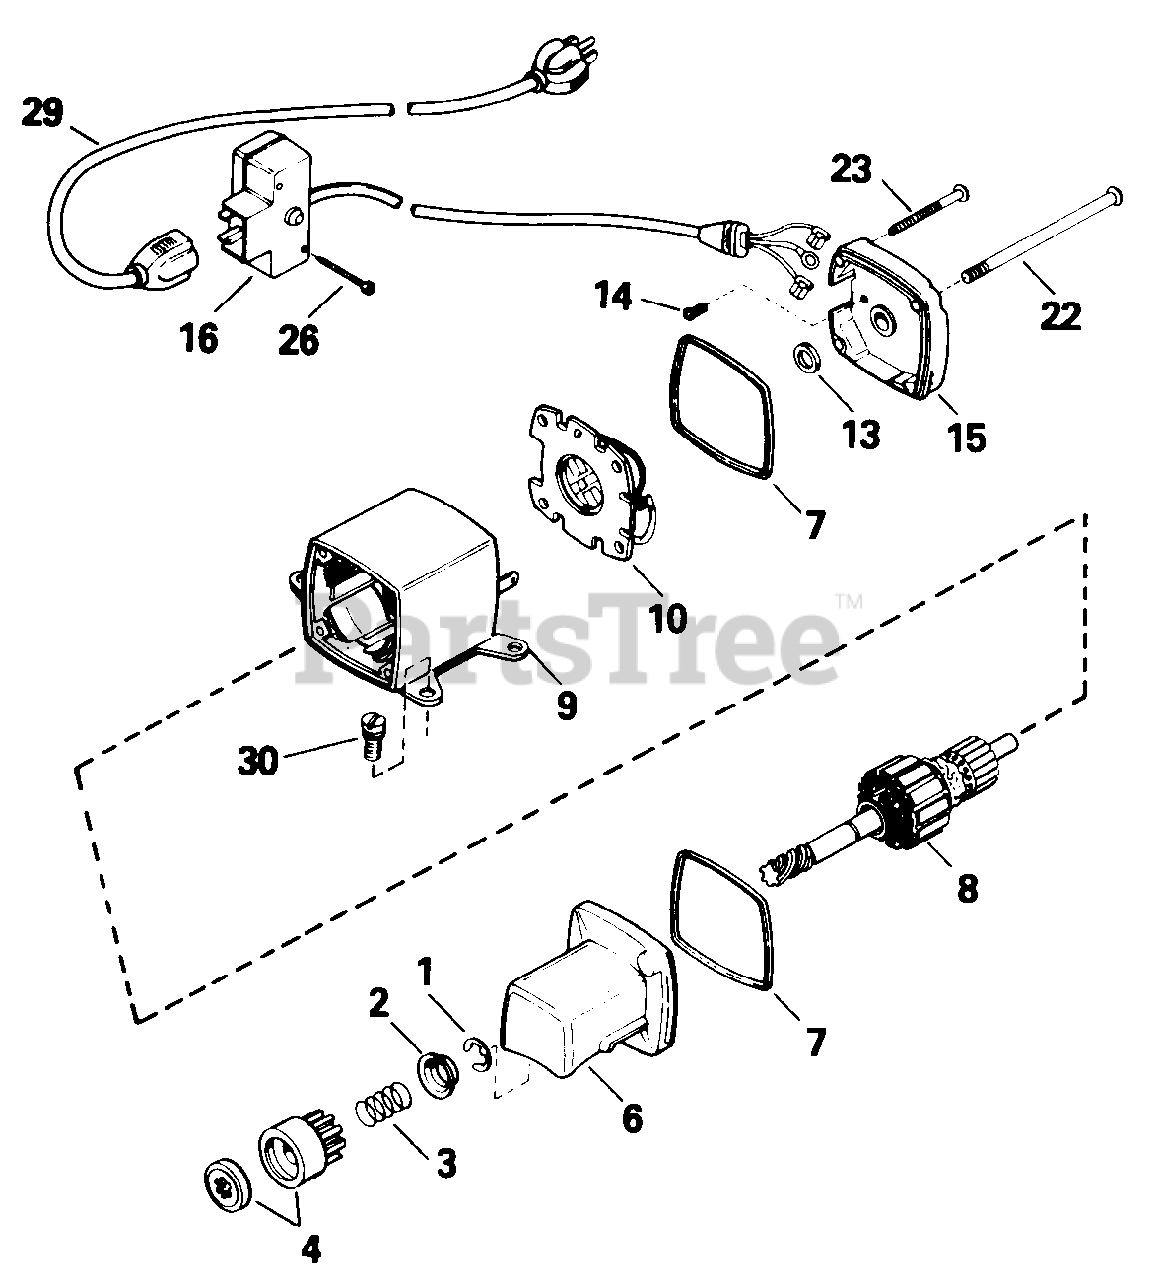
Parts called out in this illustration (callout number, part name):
1	Ring, Retainer
2	Retainer, Spring
3	Spring, Anti-Drift
4	Nut & Gear
6	Cap Ass'y., Drive End
8	Armature
9	Housing Ass'y.
10	Card Ass'y., Brush
13	Washer, Thrust
14	Screw, Ground
15	Cap Ass'y., Commutator End
16	Box Ass'y., Switch
22	Bolt, Case
23	Screw, Grounding
26	Screw, Hex Hd. Self-Tap, 6-32 x 2'/2
29	Cord, Extension
30	Screw, Hex Hd. Self-Tap, 1/4-20 x 11/16
